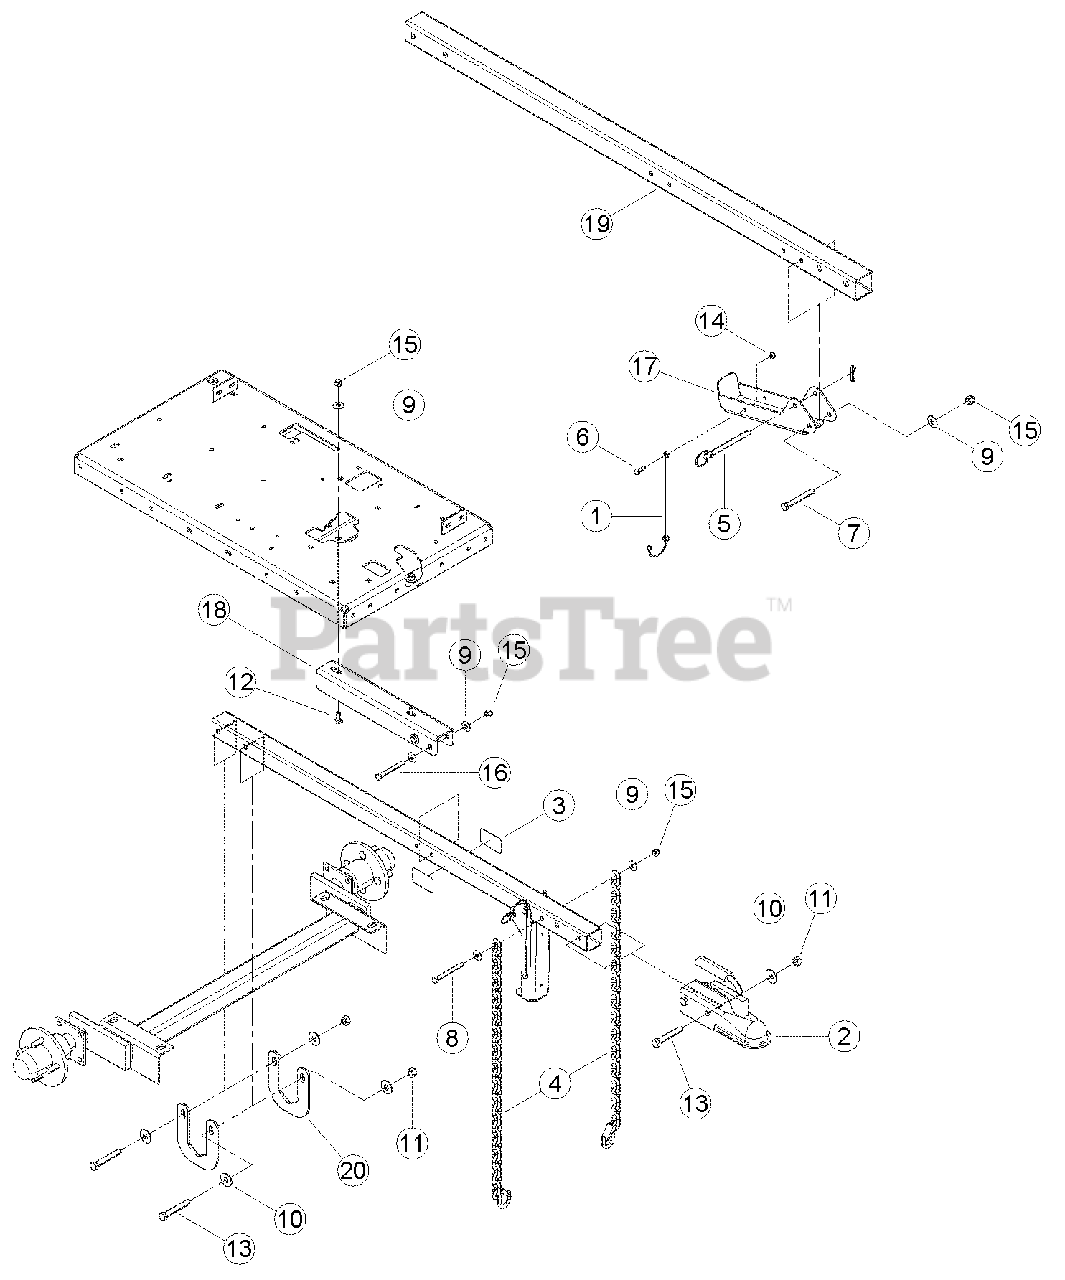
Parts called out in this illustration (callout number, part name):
1	LANYARD, NYLON
2	COUPLER, 50 MM BALL
3	REFLECTOR, WIDE ANGLE AMBER
4	CHAIN, SAFETY 5000 LB W/LATCH
5	PIN, 3/8 HITCH
6	BOLT, 1/4 X 3/4 HEX HD GR5 ZP
7	BOLT, 3/8 X 3 HEX HD GR5 ZP
8	BOLT, 3/8 X 3-1/2 HEX HD GR5 ZP
9	WASHER, 3/8 FLAT ZP
10	WASHER, 1/2 FLAT ZP
11	NUT, 1/2 CENTERLOCK GRB ZP
12	BOLT, 3/8 X 1 CRG GR5 NC ZP
13	BOLT 1/2 X 3-1/4 HCS GR5 ZP
14	NUT, 1/4 NE NYLOCK ZP
15	NUT, 3/8 NE NYLOCK ZP
16	BOLT, 3/8 X 3-1/4 HEX HD GR5 ZP
17	STAND, JACK
18	CHANNEL, HITCH POLE
19	TUBE, HITCH
20	PLATE, HITCH
